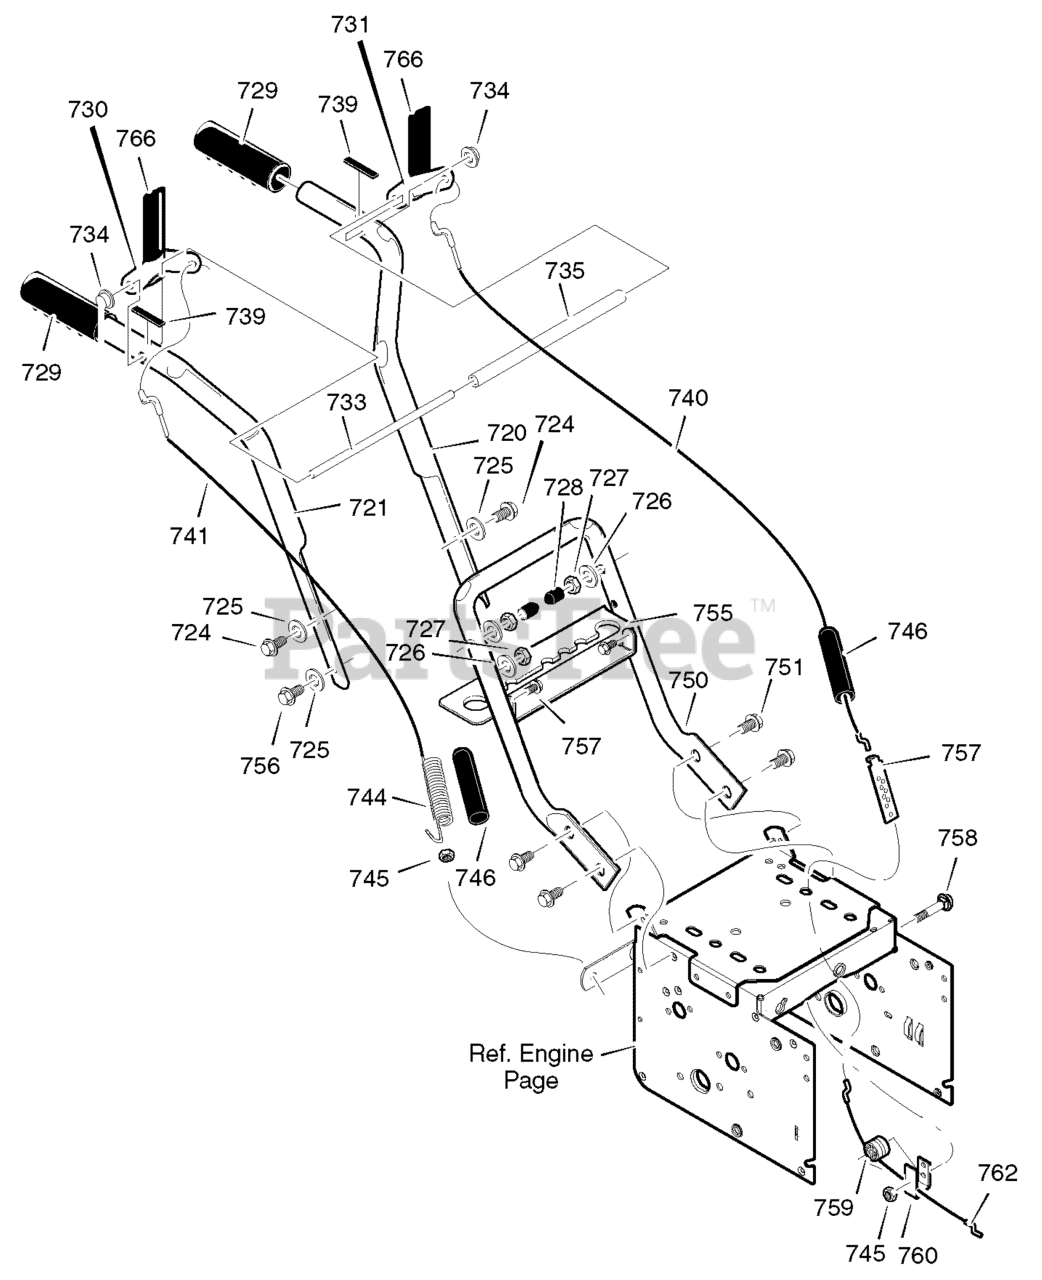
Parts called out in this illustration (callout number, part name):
720	HANDLE, UPPER LH
721	HANDLE, UPPER RH
724	SCREW, 5/16-18 x 2.75
725	WASHER, FLAT
726	WASHER, SPTLK .31X.58X.08
727	NUT, 5/16-18 REGHEX YZ
728	STOP, RED PLASTIC
729	GRIP-HANDLE FINGER
730	LEVER, ASSY CLUTCH DRIVE RH
731	LEVER, ASSY CLUTCH DRIVE LH
733	ROD, PIVOT CLUTCH
734	NUT, PUSH ON CAP
735	SPACER-HANDLE
739	BUMPER, RECTANGLE
740	CABLE, CLUTCH
741	CABLE, AUGER CLUTCH
743	BRACKET, CABLE ADJUSTER
744	SPRING, AUGER CLUTCH
745	NUT, 1/4-20 NYLOCK YZ
746	BOOT, CABLE SPRING
750	HANDLE, LOWER
751	SCREW, TAP 5/16-18 X .75
755	BRKT, GEAR SELECTOR
756	SCREW, 5/16-18 x 2.00
757	PLATE, ADJUSTING
758	BOLT, HEX 1/4-20 X 1.50
759	SPOOL-CABLE, AUGRT CLUTCH
760	BRACKET, CABLE SPOOL YZ
762	CABLE, LOWER DRIVE 12"
766	GRIP, CLUTCH HANDLE
